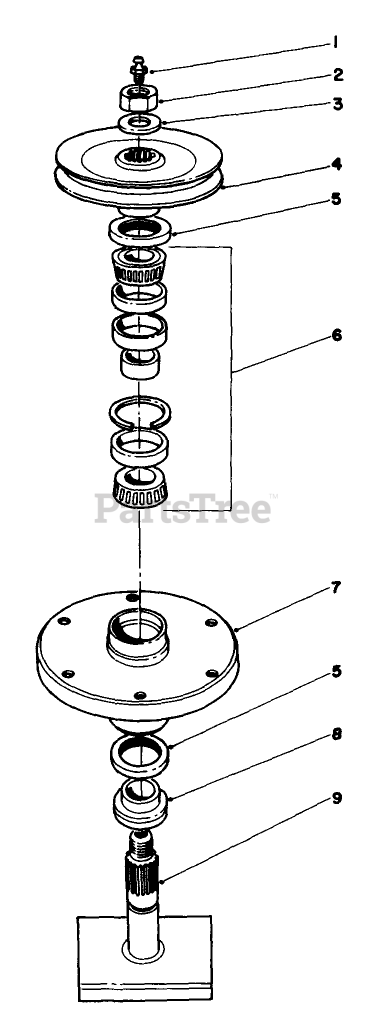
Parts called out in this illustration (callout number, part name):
1	FITTING-GREASE
2	NUT-HEX
3	WASHER
5	SEAL-OIL
6	BEARING ASM
7	HOUSING-SPINDLE
8	SPACER
9	SHAFT
